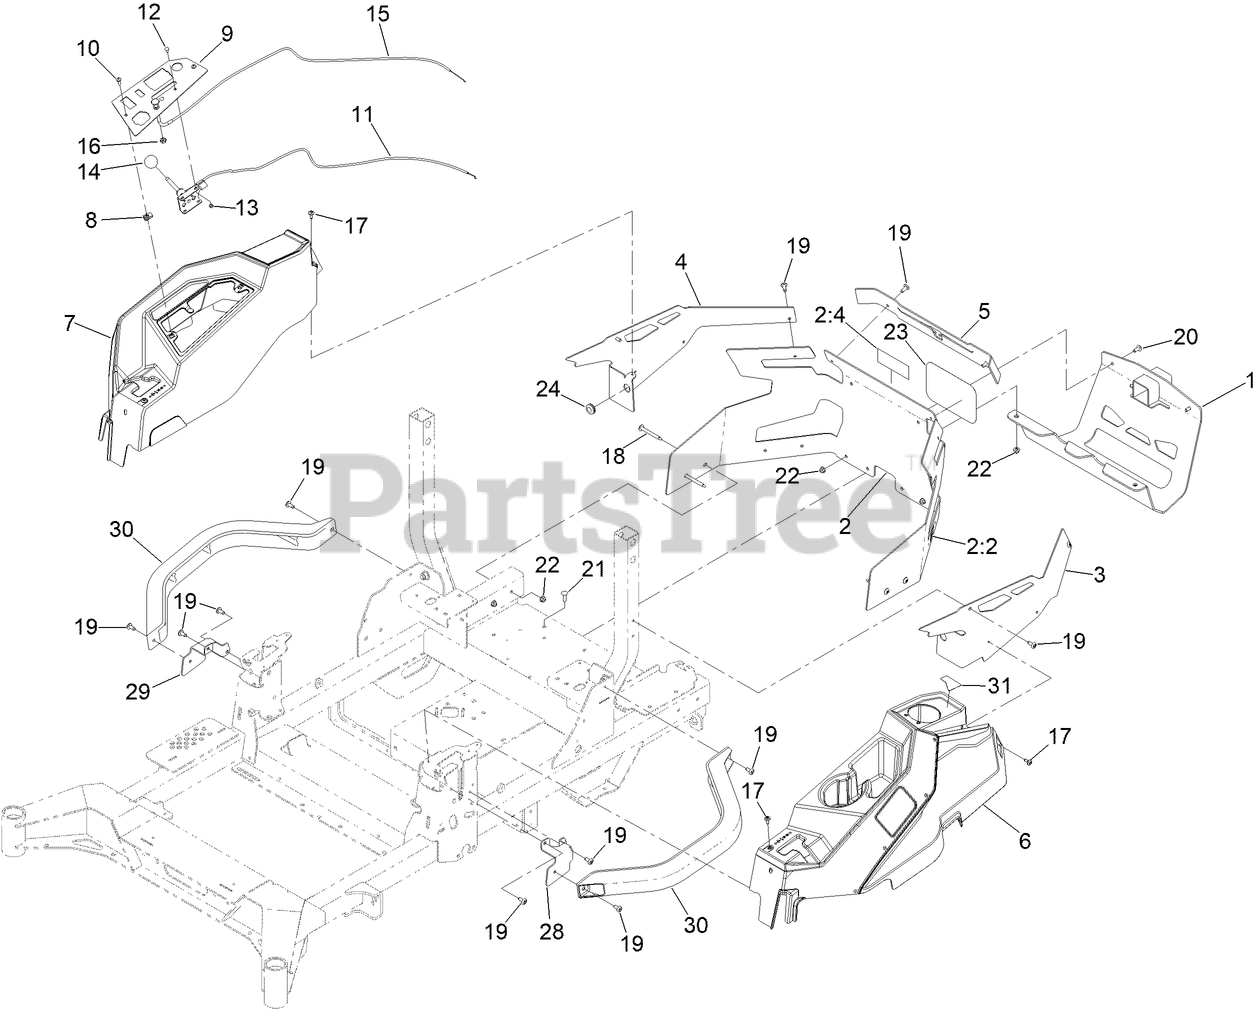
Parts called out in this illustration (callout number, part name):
1	MUFFLER GUARD ASM [BLACK]
2	REAR GUARD ASM
2:2	DECAL-WARNING
2:4	DECAL-HITCH
3	GUARD-REAR, LH
4	GUARD-REAR, RH
5	GUARD-REAR, TOP
6	LH POD ASM
7	RH POD ASM
9	PANEL-CONTROL
10	SCREW-PH
11	CABLE-CONTROL, THROTTLE
12	BOLT-CARR
13	NUT-LOCK, NI
14	KNOB-BALL
15	CABLE-CONTROL, CHOKE
16	NUT-HJ
17	SCREW-SHOULDER
18	SCREW-TORX
20	SCREW-TORX
21	SCREW-CARR
22	NUT-HF, NI
23	DECAL
24	GROMMET
28	BRACKET-MOUNT, LH
29	BRACKET-MOUNT, RH
30	TUBE-POD
31	DECAL-FUEL FILL
